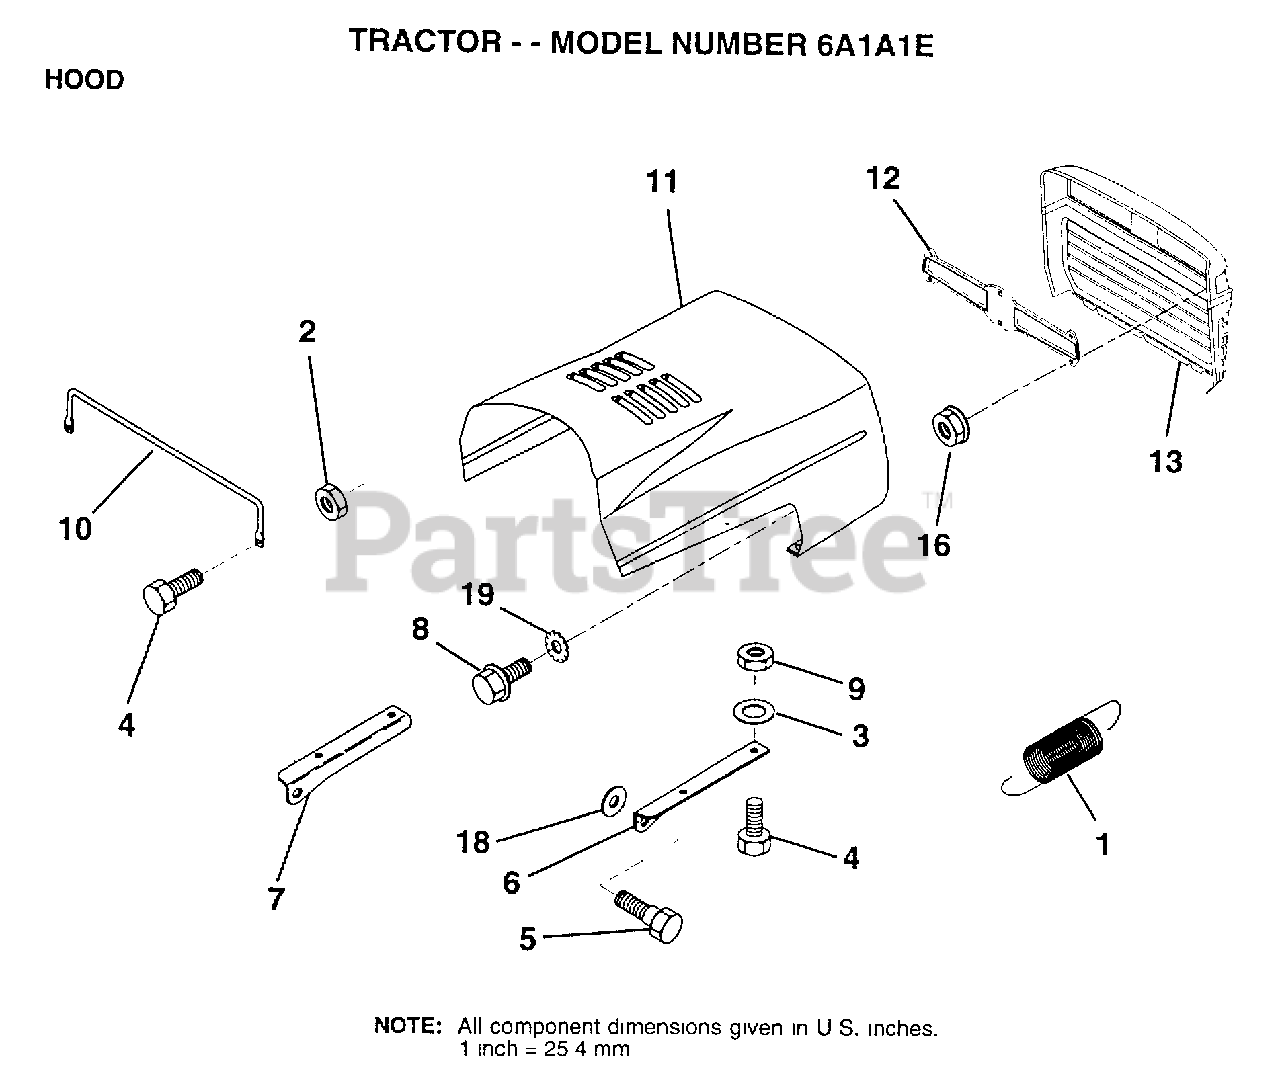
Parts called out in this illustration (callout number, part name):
1	EXT SPRING
2	NUT HXKEP 1/4X20
3	WASHER
5	BOLT.SHLD.5/16-18
6	BRKT HOOD RH
7	BRKT HOOD LH
8	SCREW SLTD HXHD
9	NUT
10	"BRACE,HOOD"
11	HOOD
13	GRILL (BLACK)
16	NUT
18	WASHER
19	LOCKWASHER GT
